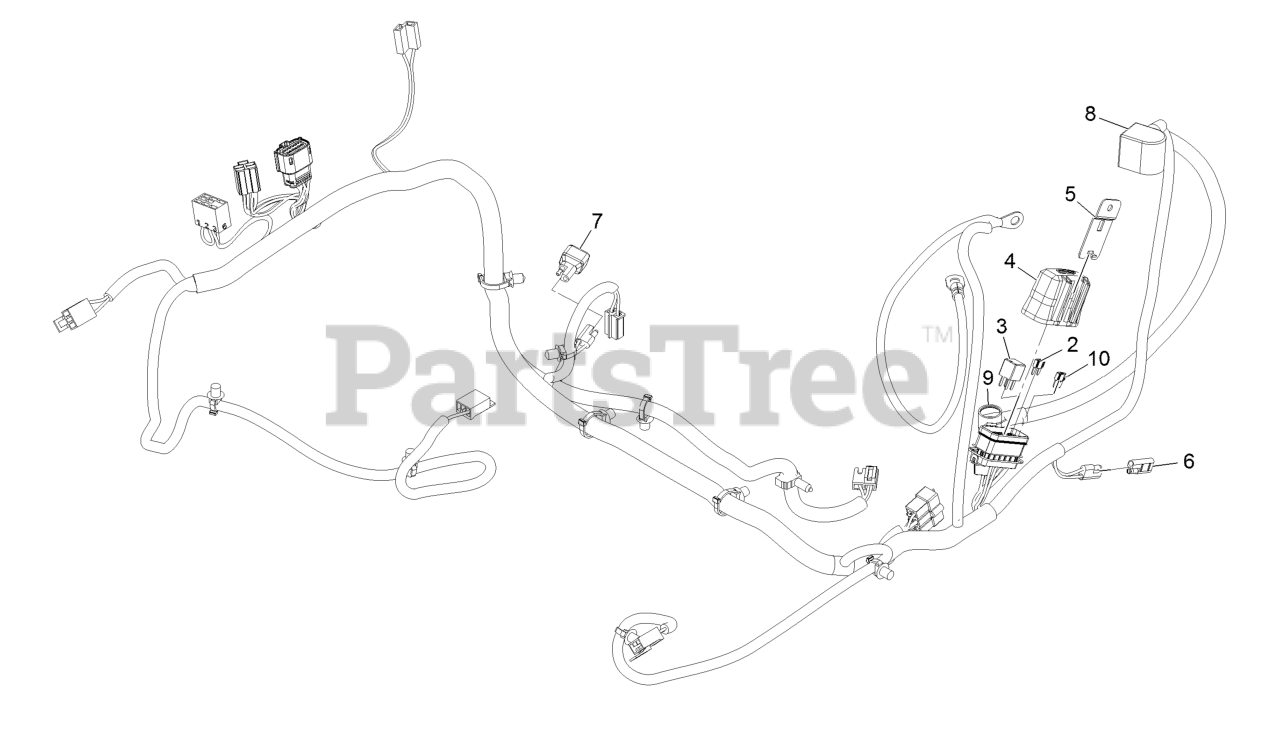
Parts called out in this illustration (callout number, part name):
2	Fuse-Mini Blade, 20 Amp
3	Relay-Micro
4	Cover-Block, Fuse
5	Clip-Mounting
6	Cap-Plug
8	Insulator-Battery
9	Insulator-Solenoid
10	Fuse-Mini Blade, 15 Amp
